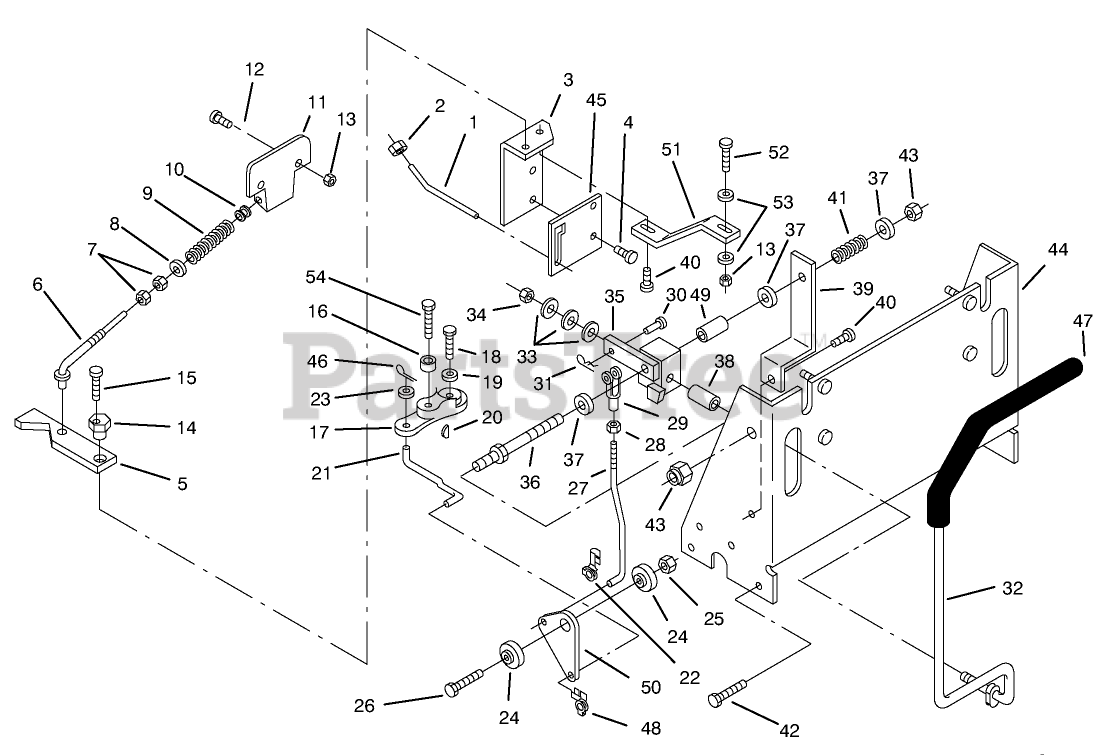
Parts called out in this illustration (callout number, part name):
1	LEVER-TOW VALVE
2	NUT-LOCK, NI
3	Bracket RH
4	SCREW-TAPTITE
5	Arm
6	ROD-NEUTRAL RETURN
7	NUT-JAM
8	WASHER-FLAT
9	SPRING COMPRESSION
10	NYLINER BUSHING
11	Bracket
12	SCREW-HSH
13	NUT-LOCK, NI
16	SPACER
17	Arm-Control, RH
18	Bolt
19	WASHER-FLAT
20	KEY WOODR 1/8X1/2 DI
21	LINK-R.H.
22	CLIP-CLEVIS L.H.
23	WASHER-FLAT
24	SPACER-CLUTCH LINK
25	NUT-LOCK, NI
26	SCREW-HH
27	ROD-HYDRO CTRL. ADJ.
28	NUT-JAM
30	PIN-CLEVIS
31	Pin-Cotter
32	R/H STRG LEVER B
33	SPRING-BELLVILLE
34	NUT-JAM
35	Lever Pivot RH
36	SHAFT-PIVOT
37	WASHER-FLAT
38	BUSHING-STR LVR PVT
39	Bracket-Retainer
40	SCREW-HWHTF
41	SPRING
42	SCREW-HWH, TAPTITE
43	NUT-LOCK, NI
44	Lever Support
45	PLATE-TOW VALVE L
46	PIN-COTTER
47	GRIP-CUSHION
48	CLIP-CLEVIS R.H.
49	BUSHING
50	PLATE-CONTROL PIV
51	Bracket-RH
52	SCREW-HH
53	WASHER-PLAIN
54	SCREW-HH
